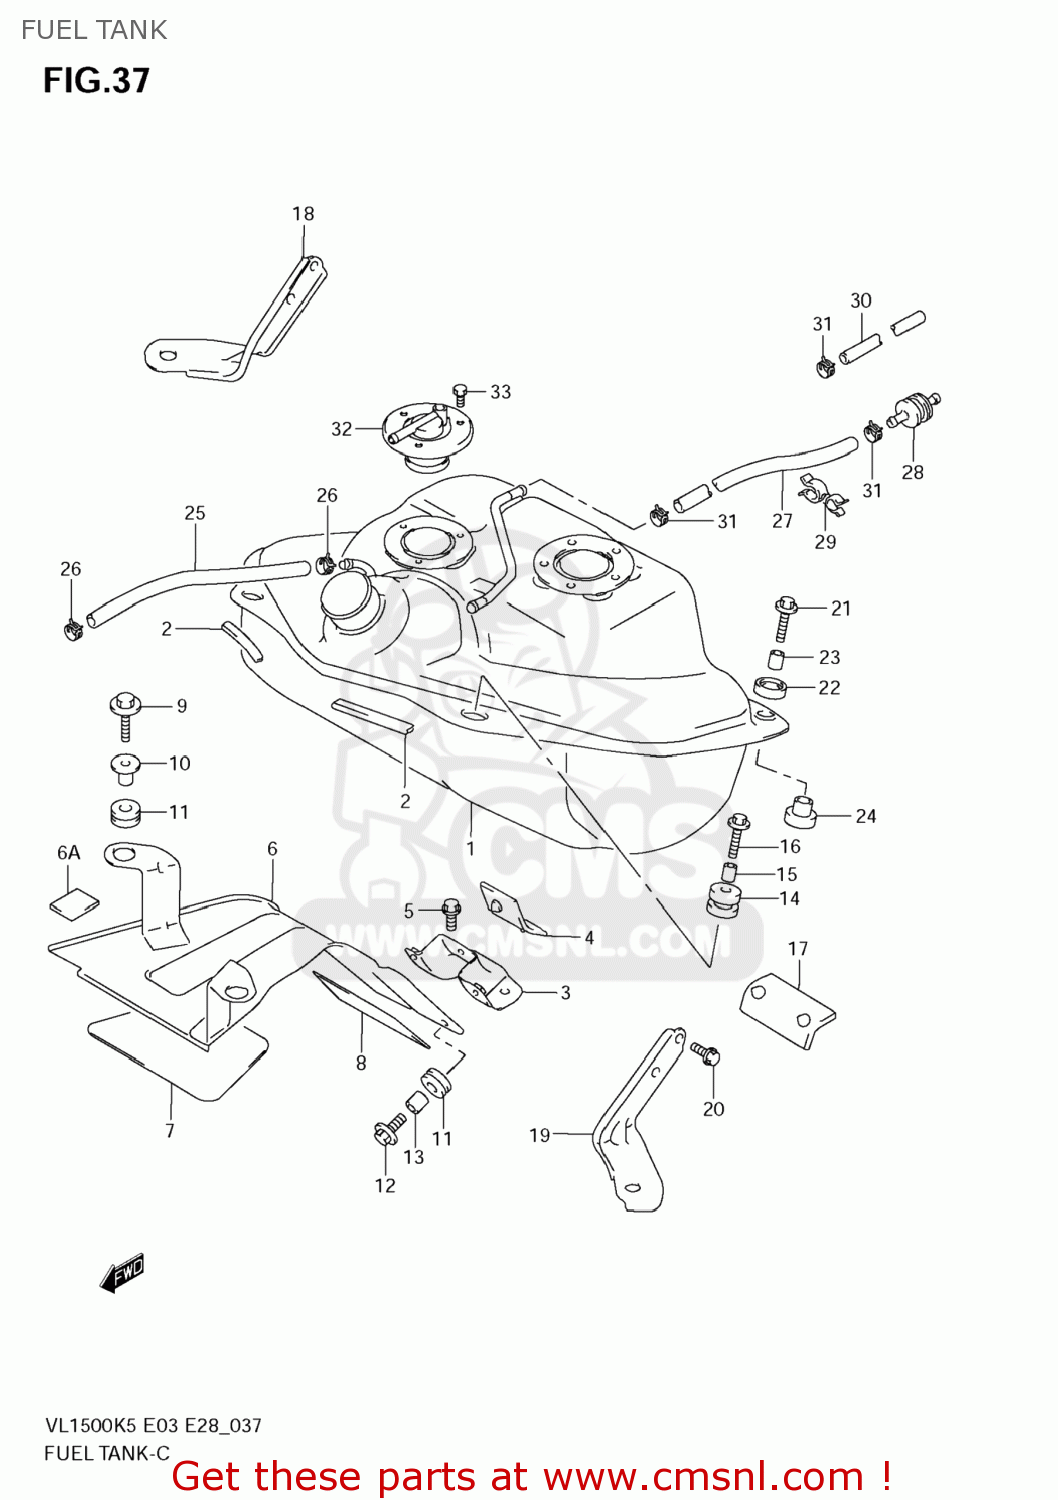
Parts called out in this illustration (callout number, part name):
1	TANK,FUEL
2	MOLDING
3	BRACKET,FUEL TANK FR
4	CUSHION,FUEL TANK FR
5	BOLT
6	COVER,FUEL TANK FR
6A	PAD
7	SHIELD,FR COVER UPR
8	SHIELD,FR COVER LWR
9	BOLT(6X30)
10	WASHER
11	CUSHION
12	BOLT(6X20)
13	SPACER(6.1X8X9.5)
14	CUSHION,FUEL TANK FR
15	SPACER(6.5X9.1X16.5)
16	BOLT(6X30)
17	CUSHION,FUEL TANK RR CTR
18	BRACKET,FUEL TANK RR,R
19	BRACKET,FUEL TANK RR,L
20	BOLT
21	BOLT(6X30)
22	CUSHION
23	SPACER(6.5X9X18)
24	CUSHION
25	HOSE(11X16X600)
26	CLIP
27	HOSE(5.4X11.4X600)
28	VALVE,2WAY CHECK
29	CLAMP
30	HOSE(5.4X11.4X600)
31	CLIP
32	VALVE,FUEL CUT
33	BOLT 5X10
